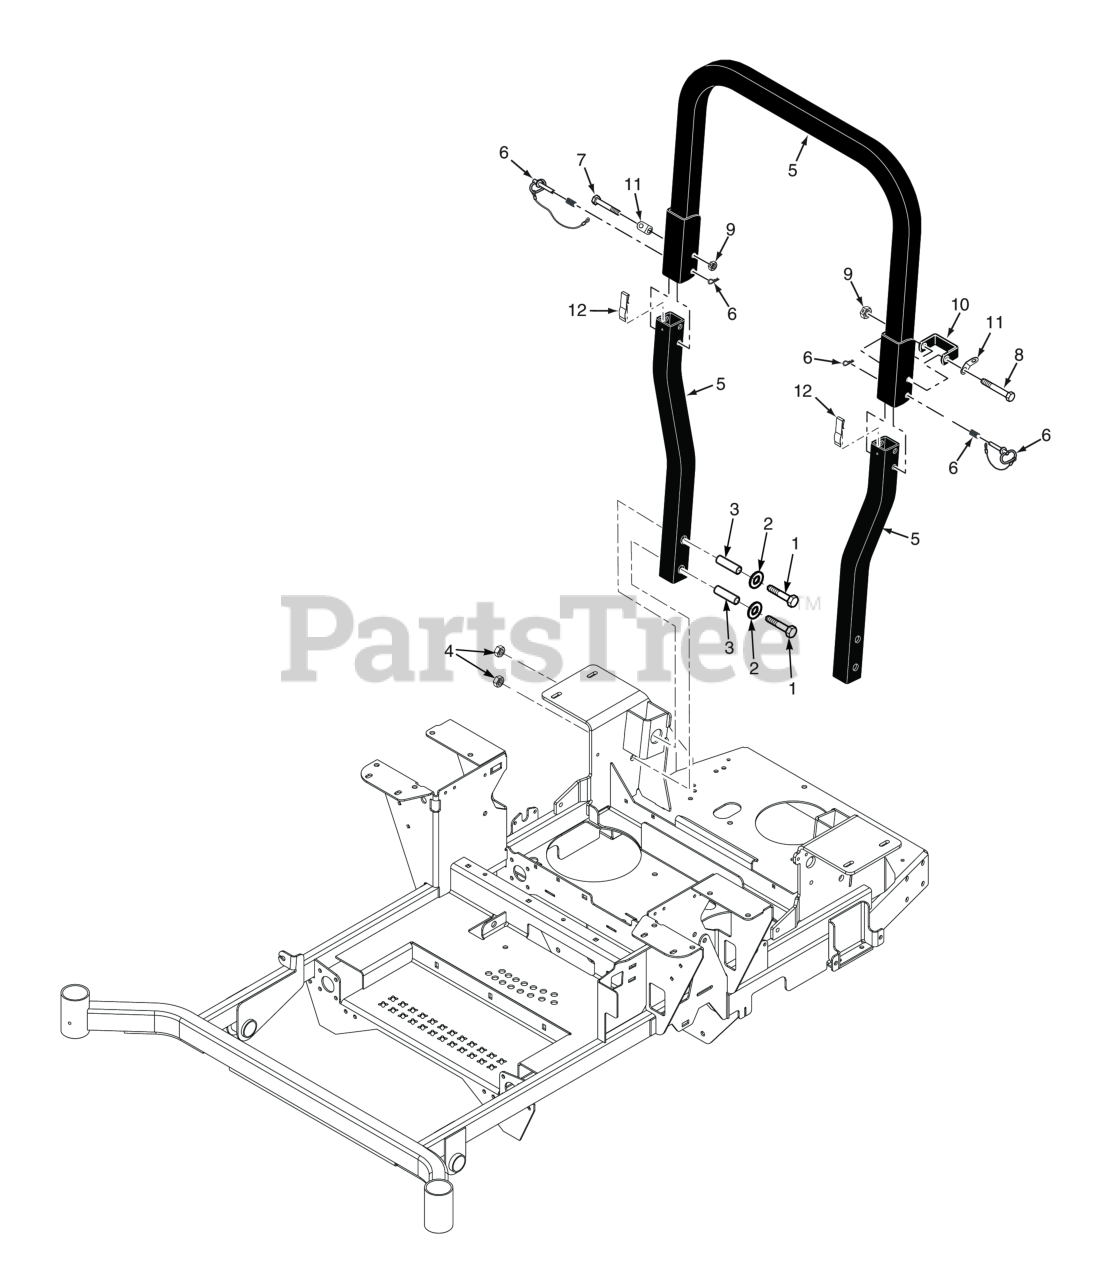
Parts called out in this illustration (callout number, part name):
1	Bolt, Hex Head 1/213 x 3" Gr. 8
2	Flatwasher, 1/2 - .531 x 1.062 x .095
3	Bushing, SFZ ROPS
4	Nut, Elastic Stop 1/2-13, (STT-52 & STTII-52)
5	ROPS, (Scag Gold)
6	Pin Assembly, ROPS Hinge
7	Bolt, Hex Head, 1/2-13 x 3-1/4"
8	Bolt, Hex Head 1/2-13 x 3-1/2"
9	Locknut, Hex 1/2-13 Center Lock
10	Stop, ROPS
11	Clip, ROPS
12	Spring, ROPS Anti-Rattle
